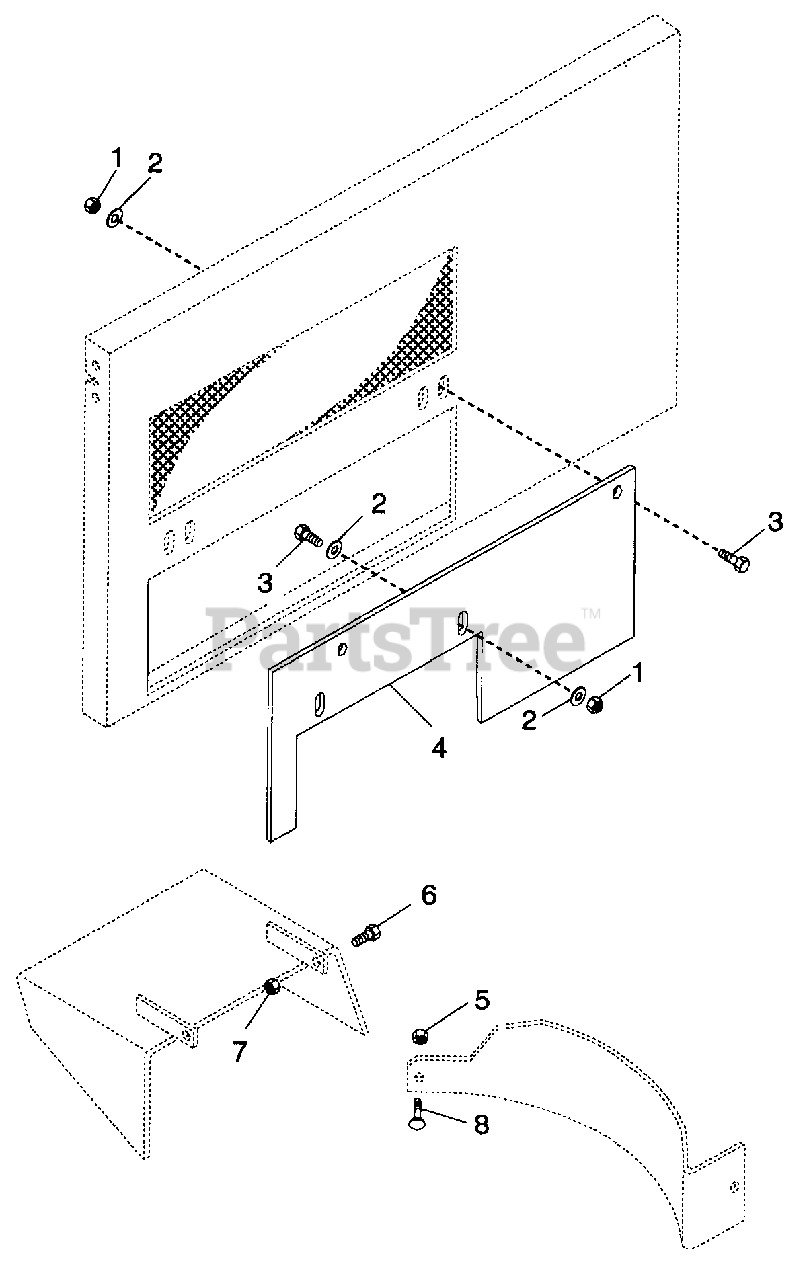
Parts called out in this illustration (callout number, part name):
1	Nut-Locking-Nylon .375-16 Grade 2
2	Washer-Flat-Steel .406 x .812 x .065
3	Bolt-Hex .38-16 x 1.00 Grade 5
4	Adapter, PRO 40
5	Nut-Locking-Nylon .250-20 Grade 2
6	Bolt-Hex .31-18 x 1.25 Grade 5
7	Nut-Locking-Nylon .312-18 Grade 2
8	Bolt-Round Head Square Neck .25-20 x .75
